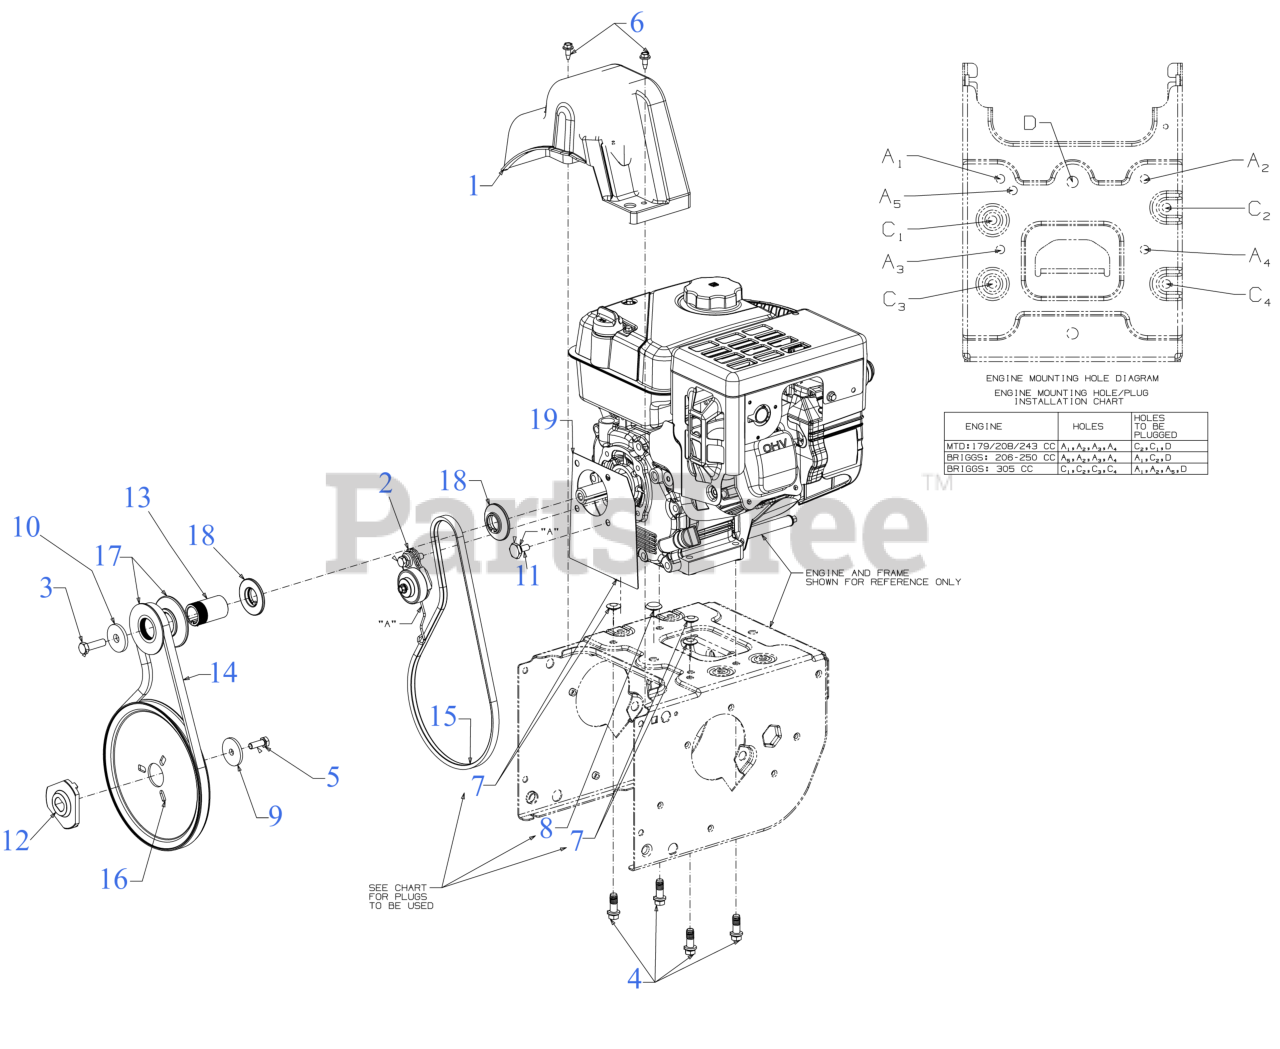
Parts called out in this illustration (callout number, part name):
1	BELT COVER (SMALL BLOCK)
2	IDLER ASSEMBLY
3	SCREW 3/8-24X1.25
4	SCREW 3/8-16 x 1
5	SCREW 5/16-24 x .875 GR5
6	SCREW 1/4-20X.625
7	PLUG-3/8 DIA ID x 3/32
8	PLUG-1/2 ID x 3/32
9	FLAT WASHER
10	FLAT WASHER .45 x 1.5 x .172 HT
11	SHOULDER SCREW
12	ADAPTER PULLEY .75 DIA W/DD
13	PULLEY SPACER
14	V-BELT .500 x 35.00LG
15	V-BELT 3L 34.18
16	AUGER PULLEY
17	HALF PULLEY 4L V x 2.6 OD
18	HALF PULLEY-3/8 V x 1.7160
